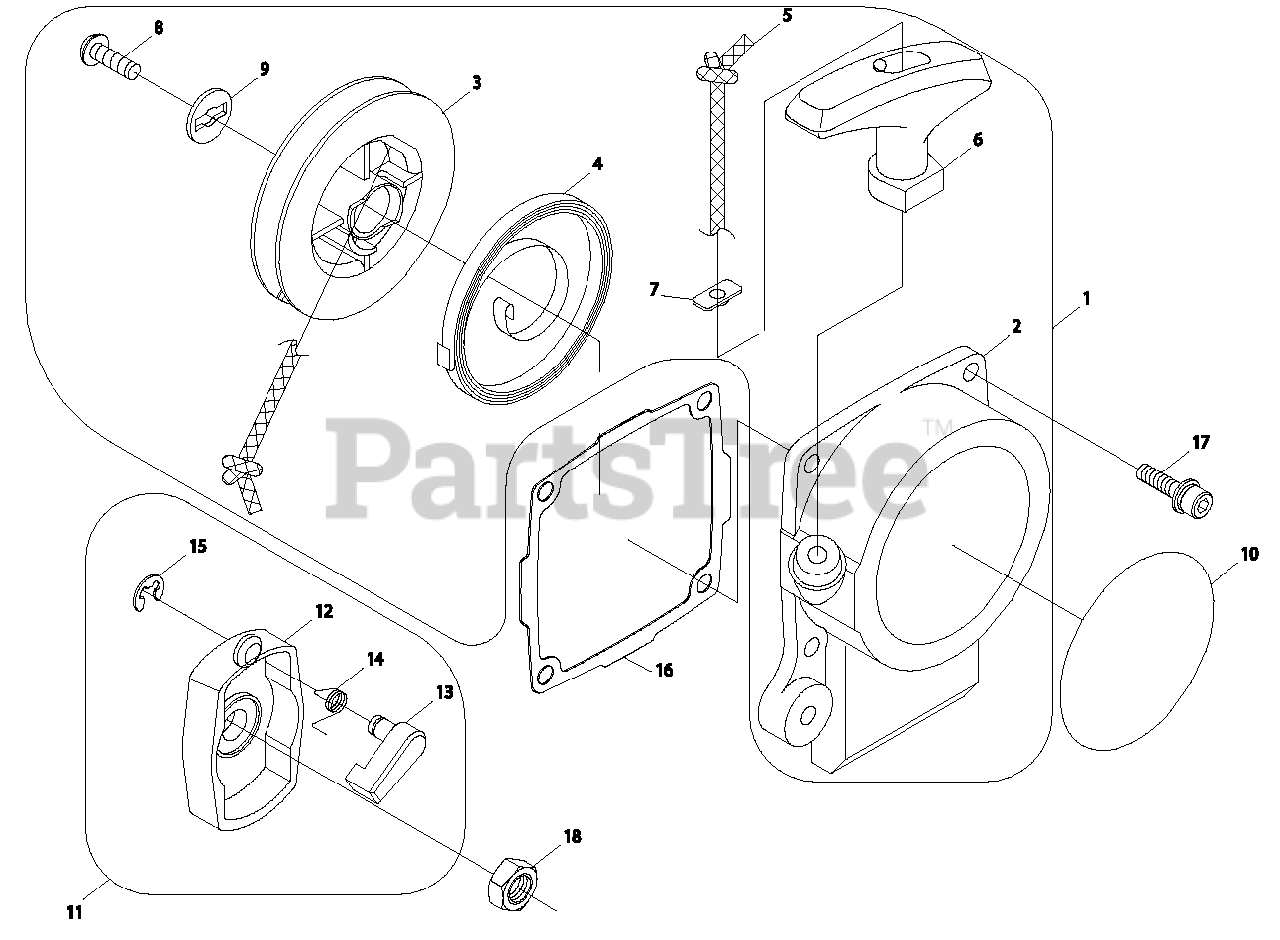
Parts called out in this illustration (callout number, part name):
1	STARTER ASSY, RECOIL
2	CASE, RECOIL STARTER
3	REEL, ROPE
4	SPRING, RECOIL
5	ROPE
6	GRIP, STARTER
7	RETAINER, ROPE
8	SCREW 5
9	WASHER
10	LABEL, TRADE
11	PULLEY ASSY, STARTER
12	PULLEY, STARTER
13	PAWL, STARTER
14	SPRING, RETURN
15	E-RING 4
16	GASKET, RECOIL STARTER
17	BOLT M5×25
18	NUT
